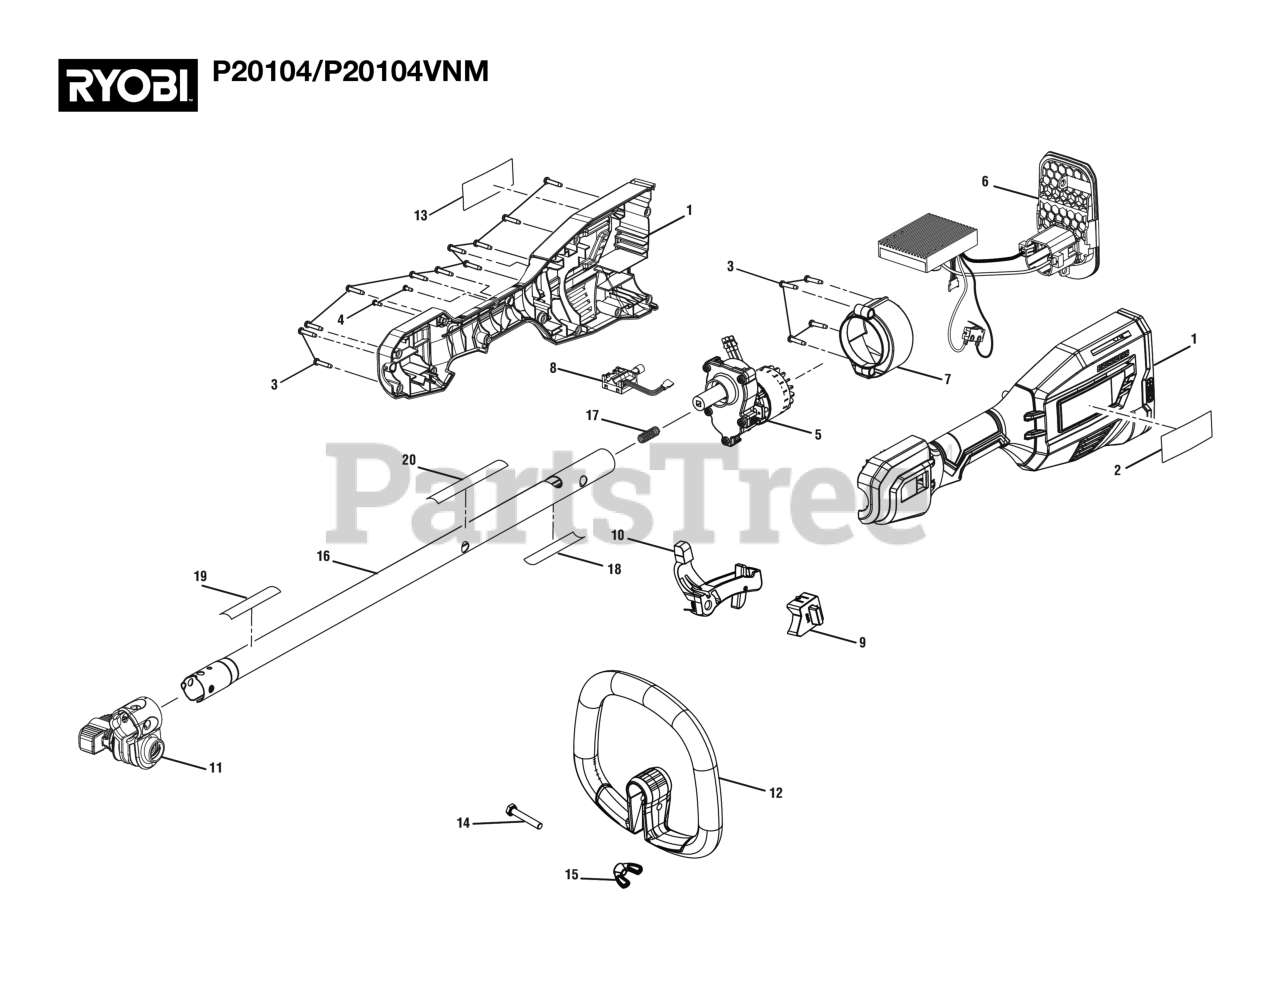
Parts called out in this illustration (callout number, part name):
1	Rear Handle Assembly
2	Logo Label
3	Screw (M4 x 18 mm, T15 Torx Pan Hd.)
4	Screw (M3 x 8 mm, Pan. Hd.)
5	Motor & Gear Box Assembly
6	Motor Controller & Switch Assembly
7	Motor Volute Assembly
8	Variable Speed Switch
9	Hi-Lo Switch Cover
10	Switch Trigger Assembly
11	Boom Clamp Assembly
12	Auxiliary Handle Assembly
13	Data Label (P20104VNM)
14	Screw (1/4-20 x 40 mm, Cap Hex Hd.)
15	Wing Nut (1/4-20, Plastic)
16	Boom Assembly (Inc. Key Nos. 19-22, P20104VNM)
17	COMPRESSION SPRING
18	Warning Label (French/Spanish)
19	Attachment Label
20	Warning Icons Label
